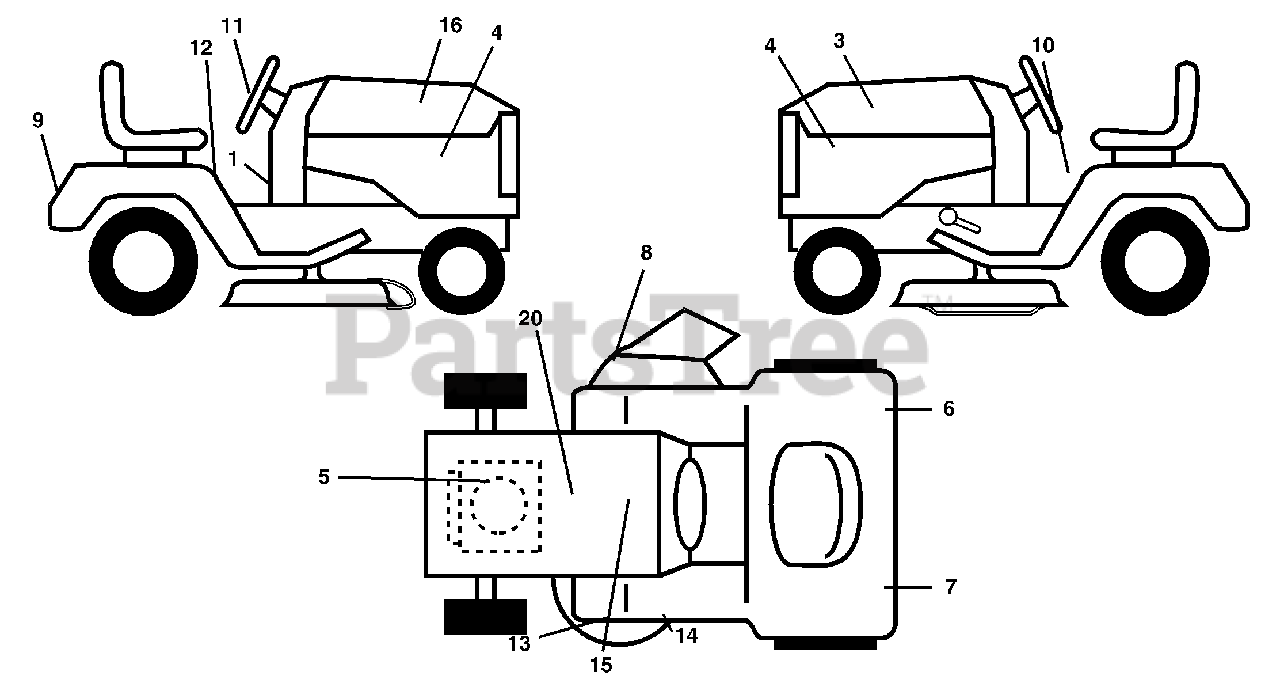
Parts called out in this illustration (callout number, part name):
1	Decal Dash
3	Decal Hood LH
4	Decal Side Panel
5	Decal HP Engine
6	Decal Reflector Rh
7	Decal Reflector Lh
8	Decal Warning Mower
9	Decal Fender Logo
10	Decal Fender Danger E/F
11	Decal Ins Strg Whl
12	Decal Fender Oper Cruise
13	Decal Deck Caution
14	Decal V-Belt Schematic
15	Decal Replace
16	Decal Hood Rh
20	Decal Bat Dan/Psn
